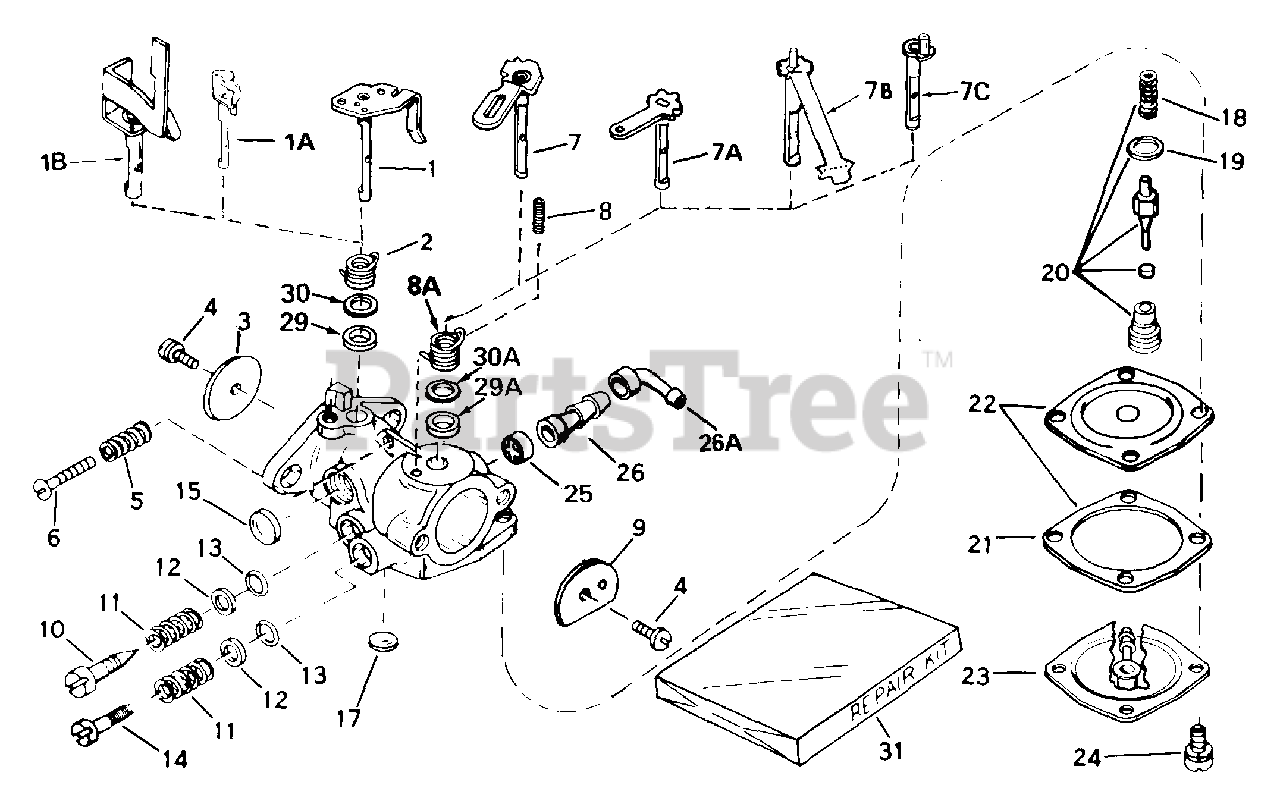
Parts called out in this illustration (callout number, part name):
1	"Shaft & Lever Assy., Throttle
2	Spring, Throttle return
3	Shutter, Throttle
4	Screw, Throttle & Choke shutter
5	Spring, Idle reg. screw
6	Screw, Idle reg.
7A	Shaft & Lever Assy., Choke
8	Spring, Choke positioning
9	Shutter, Choke
10	Screw, Adj.
11	Spring, Adj. screw
12	Washer, Adj. screw
13	"O" Ring, Adj. screw
15	Plug, Welch
17	Plug, Welch
18	Spring, Valve
19	Gasket, Valve seat
20	Inlet Needle, Seat, Gasket & Spring A ssy.
21	Gasket, Diaphragm
22	Diaphragm Assy.
23	Cover Assy., Diaphragm
24	Screw, Cover
25	Valve, Check
26A	Fitting, Fuel inlet
31	Repair Kit
